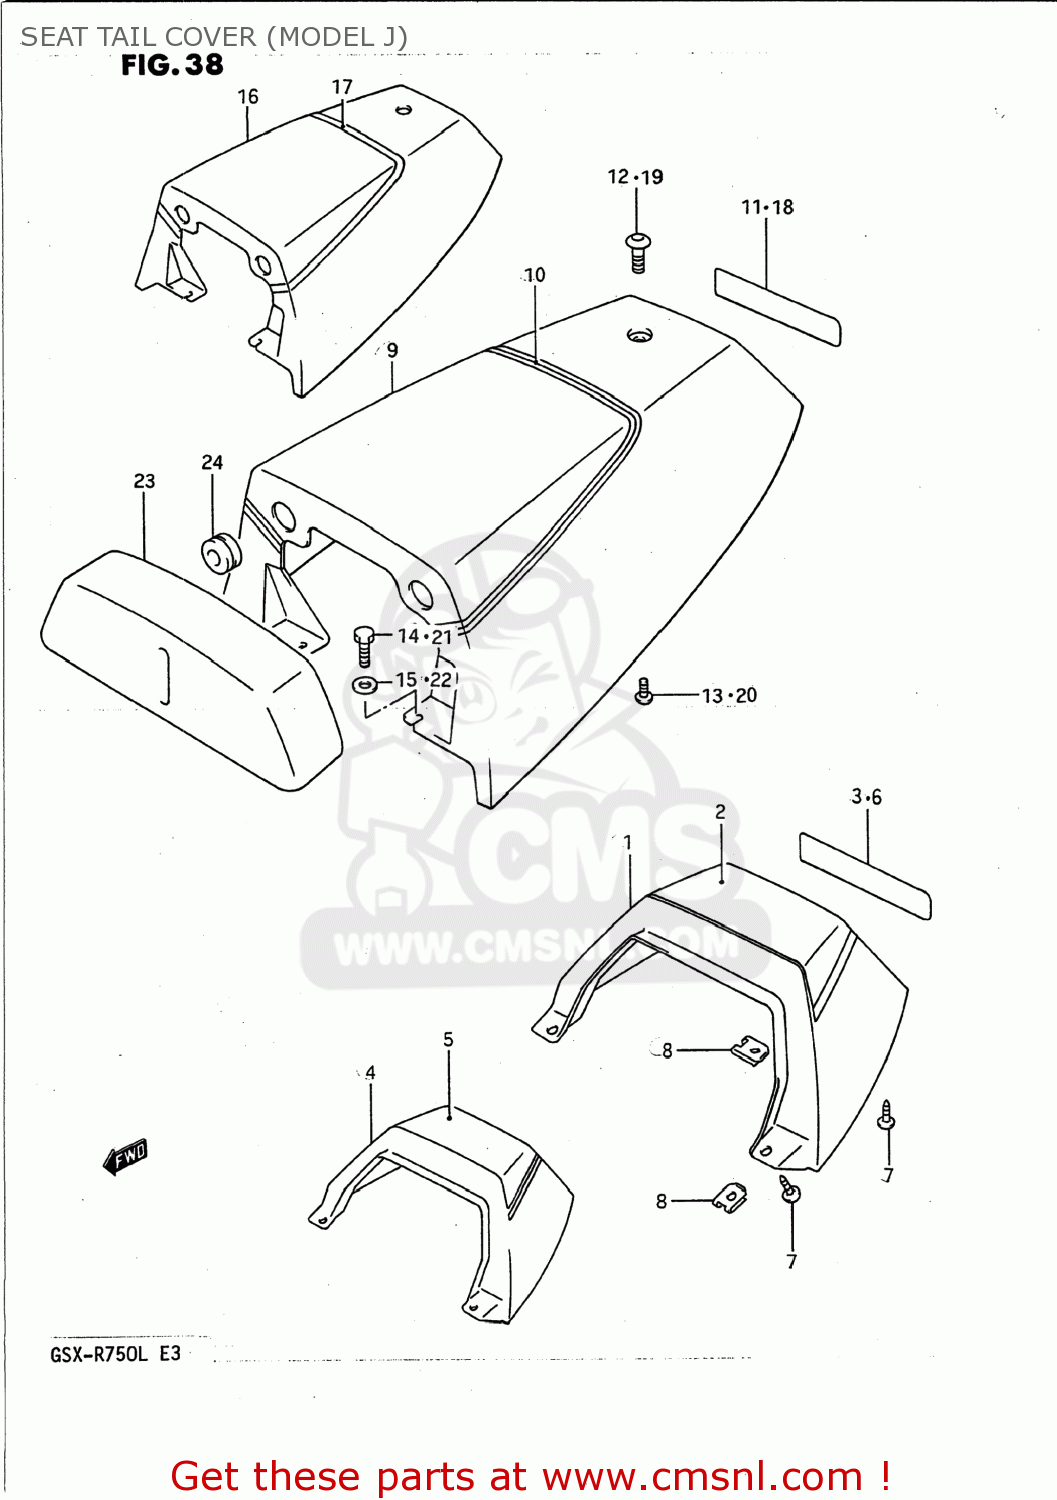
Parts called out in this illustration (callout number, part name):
1	COVER COMP,SEAT TAIL
2	TAPE,SEAT TAIL COVER
3	EMBLEM
4	COVER COMP,SEAT TAIL
5	TAPE,SEAT TAIL COVER
6	EMBLEM
7	SCREW
8	NUT
9	BOX ASSEMBLY,SEAT TAIL
10	TAPE,SEAT TAIL BOX
11	EMBLEM
12	SCREW(6X16)
13	SCREW
14	BOLT,M6X1X20
15	WASHER,LOCK
16	BOX ASSEMBLY,SEAT TAIL
17	TAPE,SEAT TAIL BOX
18	EMBLEM
19	SCREW(6X16)
20	SCREW
21	BOLT,M6X1X20
22	WASHER,LOCK
23	BACKREST,SEAT
24	CUSHION
